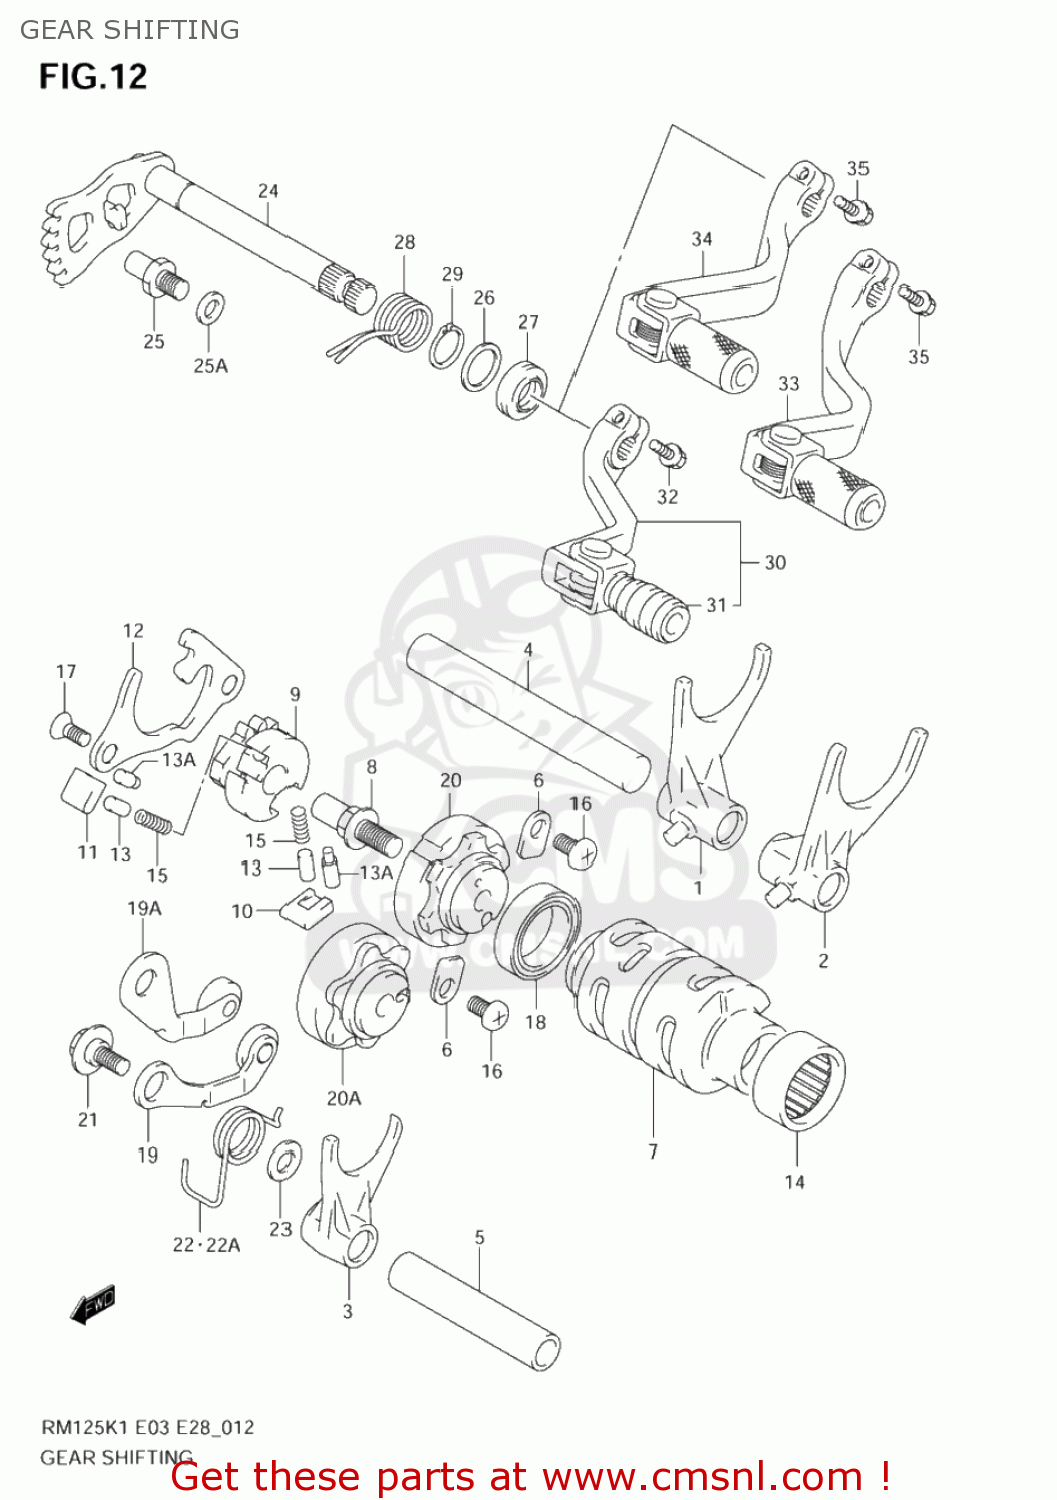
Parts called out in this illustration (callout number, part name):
1	FORK,GEAR SHIFT NO.1
2	FORK,GEAR SHIFT NO.2
3	FORK,GEAR SHIFT NO.3
4	SHAFT,GEAR SHIFT FORK(L:95)
5	SHAFT,GEAR SHIFT FORK(L:60)
6	RETAINER
7	CAM,GEAR SHIFT
8	PIN,SHIFT CAM DRIVEN GEAR
9	GEAR,GEAR SHIFT CAM DRIVEN
10	PAWL,GEAR SHIFT NO.1
11	PAWL,GEAR SHIFT NO.2
12	LIFTER,GEAR SHIFT POLE
13	PIN(5X8)
13A	PIN
14	BEARING(25X32X12)
15	SPRING
16	SCREW
17	SCREW
18	BEARING
19	STOPPER,SHIFT CAM
19A	STOPPER,SHIFT CAM
20	PLATE,SHIFT CAM STOPPER
20A	PLATE,SHIFT CAM STOPPER
21	BOLT(6X14.3)
22	SPRING
22A	SPRING,SHIFT CAM STOPPER
23	WASHER
24	SHAFT,GEAR SHIFT
25	STOPPER,GEAR SHIFT ARM
25A	SHIM(8.8X14X1)
26	SHIM(14X20X1)
27	SEAL,OIL(14X22X6)
28	SPRING
29	CIRCLIP
30	LEVER ASSY,GEA
31	RUBBER,GEAR SHIFT PEDAL
32	SCREW
33	LEVER ASSY,GEAR SHIFT
34	LEVER ASSY,GEA
35	BOLT,6X20
